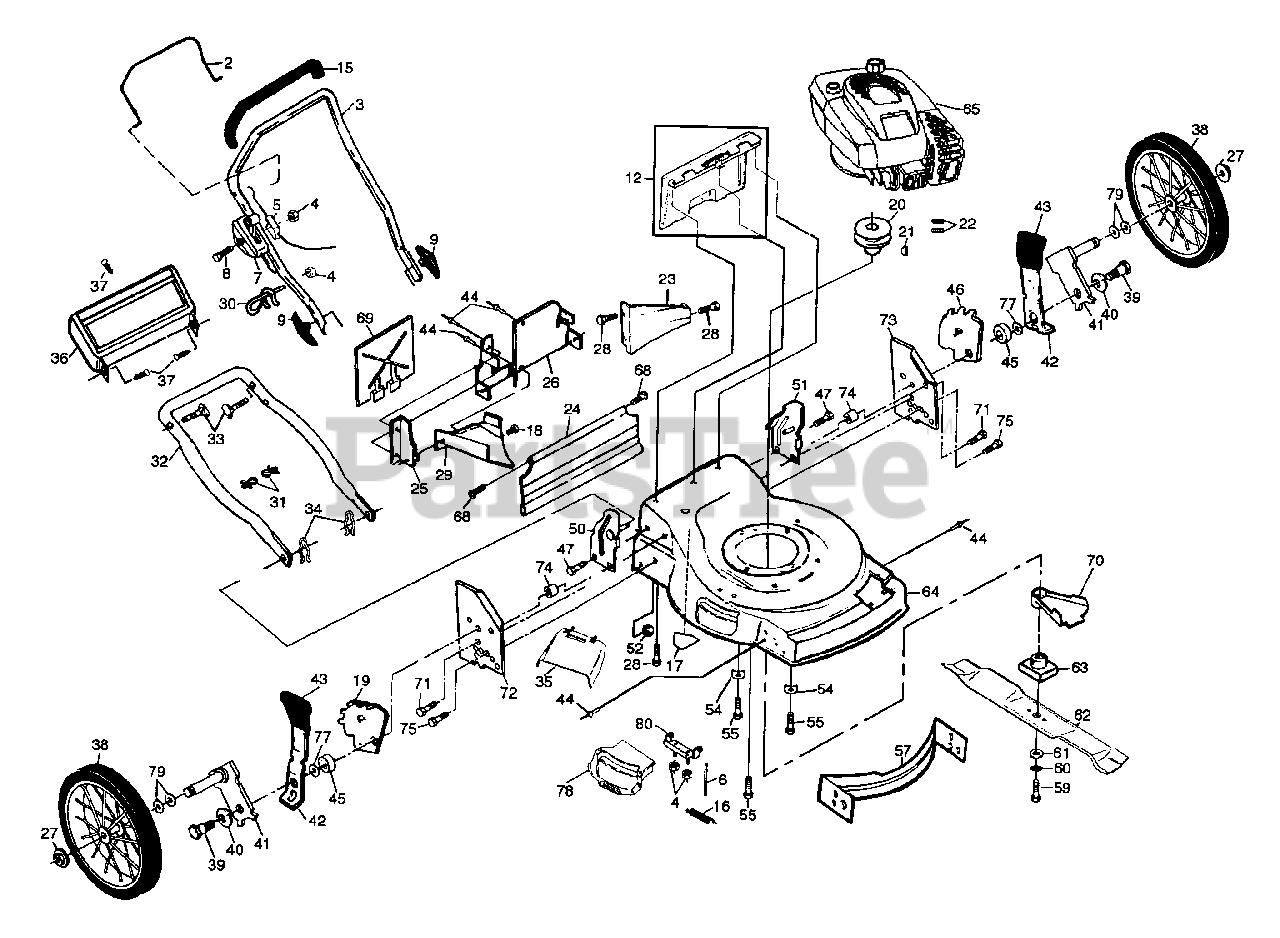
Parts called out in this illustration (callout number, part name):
2	Control Bar
3	Upper Handle
4	Locknut
5	Engine Zone Control Cable
7	Throttle Control
8	Hex Washer Head Screw 1/4-20 x 2-1/8
9	Handle Knob
12	Rear Door Kit
15	Handle Grip
16	Hinge Spring
17	Danger Decal
19	Wheel Adjusting Bracket
20	Engine Pulley
21	Hi Pro Key #505
22	Set Screw 1/4-20 x 5/16
23	Rear Baffle
24	Rear Skirt
25	Side Baffle
26	Back Plate
27	Flanged Locknut
28	Screw Hex Head 1/4-20 x 1/2
29	Discharge Baffle
30	Rope Guide
31	Wire Tie
32	Lower Handle
33	Handle Bolt
34	Hairpin Cotter
35	Clip-on Discharge Deflector
36	Trim Plate Assembly
37	Push-in Fastener
38	Wheel & Tire Assembly
39	Shoulder Bolt
40	Spring Washer
41	Axle Arm
42	Selector Spring
43	Selector Knob
45	Spacer
46	Wheel Adjusting Bracket
47	Self-tapping Screw 5/16-18 x 3/4
48	Screw 1/4-20 x 1
50	Handle Bracket (Right)
51	Handle Bracket (Left)
52	Locknut 3/8-16
54	Engine Washer
55	Hex Head Thread Rolling Screw 3/8-16 x 1-1/8
57	Front Baffle
59	Hex Head Machine Screw 3/8-24 x 1-3/8 Gr. 8
60	Helical Lock Washer
61	Hardened Washer
63	Blade Adapter
64	Lawn Mower Housing Kit
65	Engine
68	Hinge Screw
69	Mulcher Plate
70	Debris Shield
71	Thread Cutting Screw 5/16 - 18 x 1-1/5
72	Support Bracket (RH)
73	Support Bracket (LH)
77	Flat Washer
78	Combi-cut Door
79	Wave Washer
80	Hinge Bracket
81	Cable Clip
